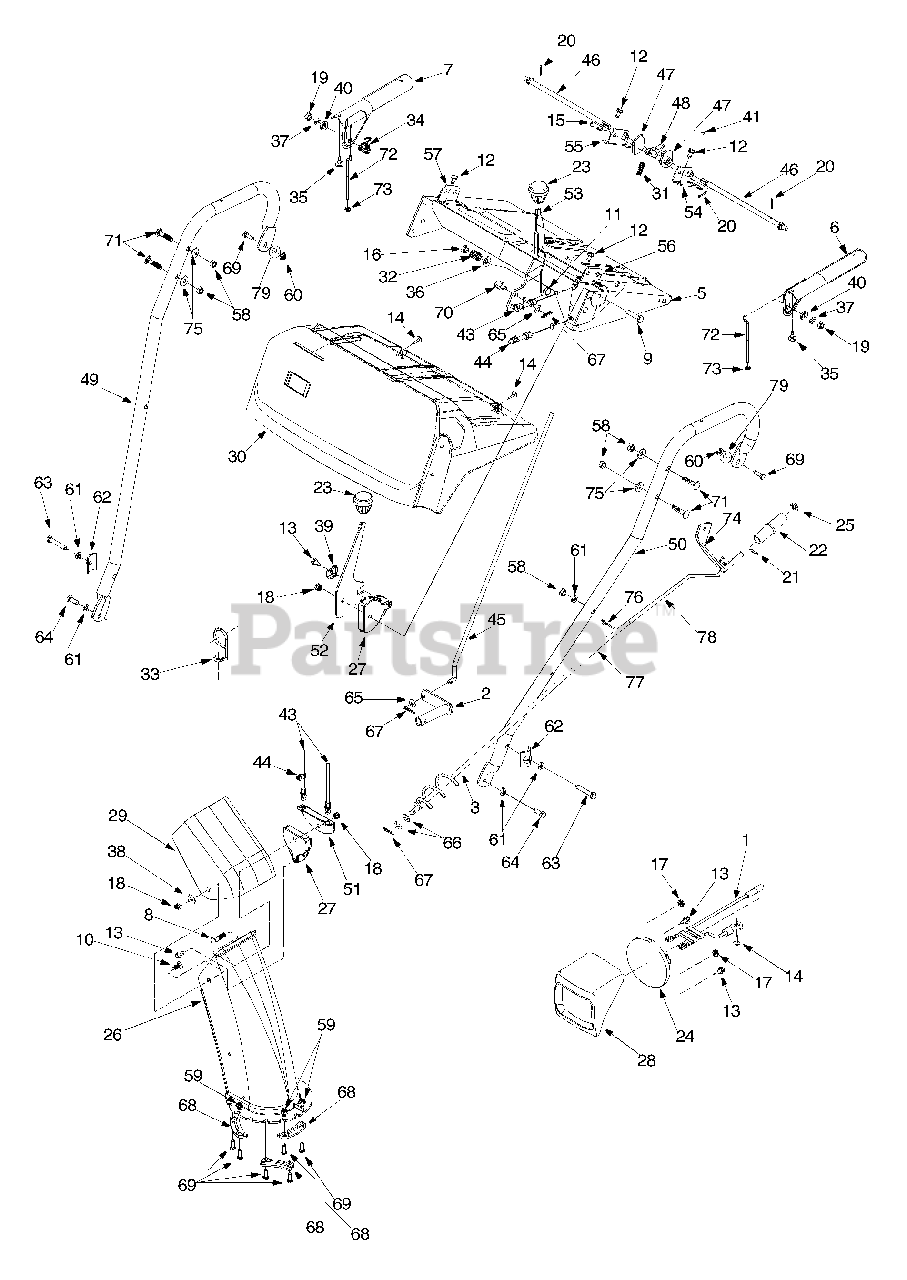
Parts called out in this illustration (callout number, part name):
1	Harness for Headlight
2	Shift Arm Assembly
5	Handle Panel Assembly w/ Tilt: Polo Green
6	Handle Assembly Engagement (L.H.) Red
7	Handle Assembly Engagement (R.H.) Red
8	Carriage Bolt 5/16-18 x 1.50
9	Hex Bolt 5/16-18 x 1.5
10	Carriage Bolt 5/16-18 x.75
11	Hex Screw 3/8-24 x 1.5
12	Hex Washer Hd. TT Screw 1/4-20 x 0.5"
13	Hex AB Tap Screw 1/4 x .62
14	Hex B-Tapp Screw # 10-16 x .62
15	Clevis Pin
16	Hex Ins. Lock Nut 3/8-24
17	Self-Threading Nut
18	Lock Nut 5/16-18
19	Hex Nut
20	Cotter Pin
21	Roll Pin
22	Chute Crank Knob
23	Shift Knob: Red
24	Headlight
25	Push Cap
26	Lower Chute
27	Cable Guide
28	Headlight Bezel
29	Upper Chute
30	Handle Panel
31	Compression Spring
32	Compression Spring
33	Cable Control Wire
34	Torsion Spring
35	Rubber Bumper
36	Bell Washer .380 x .880 x .062
37	Lock Washer 5/16 I.D.
38	Washer 5/6 I.D.
39	Special Washer
40	Special Washer
41	Grease
42	Chute Deflector Control Cable
43	Chute Deflector Cable w/ Clip
44	Shift Rod
45	Cam Rod
46	Cam Handle Lock
47	Pawl Handle lock
48	Right Handle: Powder Black
49	Left Handle: Powder Black
57	Hex Nut 5/16-18 Thd.
58	Hex Flange Locked Nut 1/4-20 Thd.
59	Hex Nut 1/4-20
60	Lock Washer 5/16
61	Flat Washer 5/16
62	Handle Tab
63	Hex Bolt 5/16-18 x 1.75 Gr.5
64	Hex Bolt 5/16 x 3/4
65	Flat Washer 3/8 x .738 x .063
66	Hairpin Clip
67	Chute Flange Keeper
68	Hex Bolt 1/4-20 x 0.75" Gr.5
69	Ferrule
70	Carriage Bolt 5/16-18 x 1.50
71	Z Fitting
72	Hex Nut # 10-24
74	Cupped Washer
75	Hairpin Clip
76	Spacer
78	Bell Washer
79	Roll Pin
